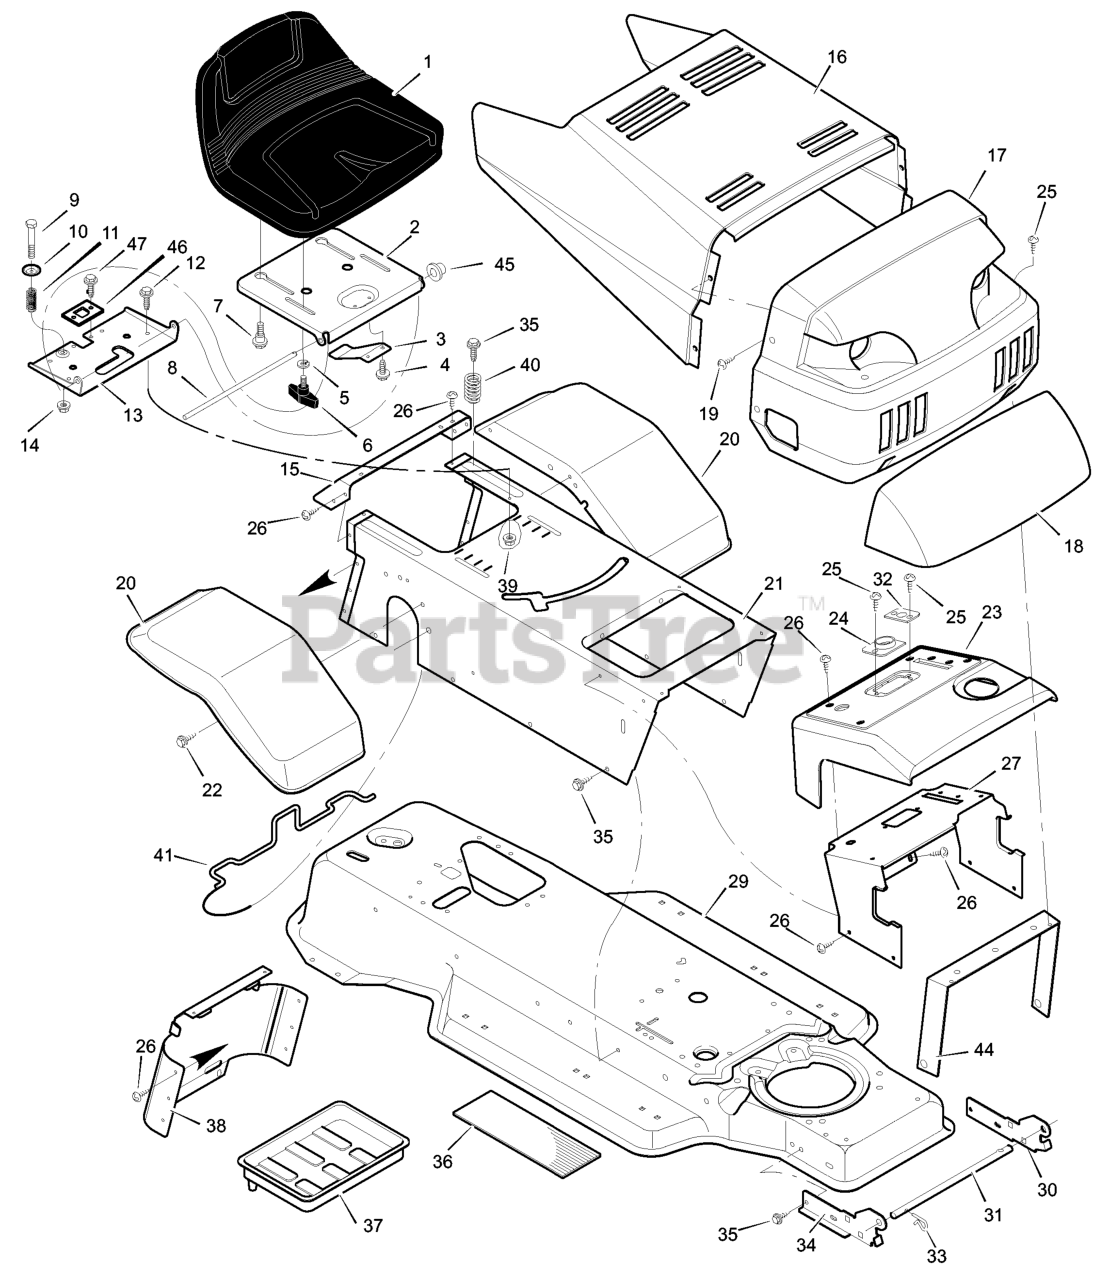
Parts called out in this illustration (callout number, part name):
1	Seat
2	Support, Seat
3	Spring, Seat
5	Washer
6	Bolt, Wing
8	Rod, Pivot
9	Bolt, Shoulder
11	Spring, Compression
12	Bolt, Hex
13	Bracket, Pivot
15	Fender, Apron
17	Grille Assembly
21	Console Assembly
23	Dash Panel
24	Bearing, Steering
26	Screw
27	Support, Dash
29	Frame Assembly
30	Bracket, Left Grille
31	Rod, Pivot
32	Bearing
33	Pin, Hair
34	Bracket, Right Grille
37	Tray, Battery
38	Cap, Console
39	Nut
40	Spring, Compression
41	Clamp, Battery
44	Brace, Grille
45	Cap, Push On
46	Plate Assembly, Switch
